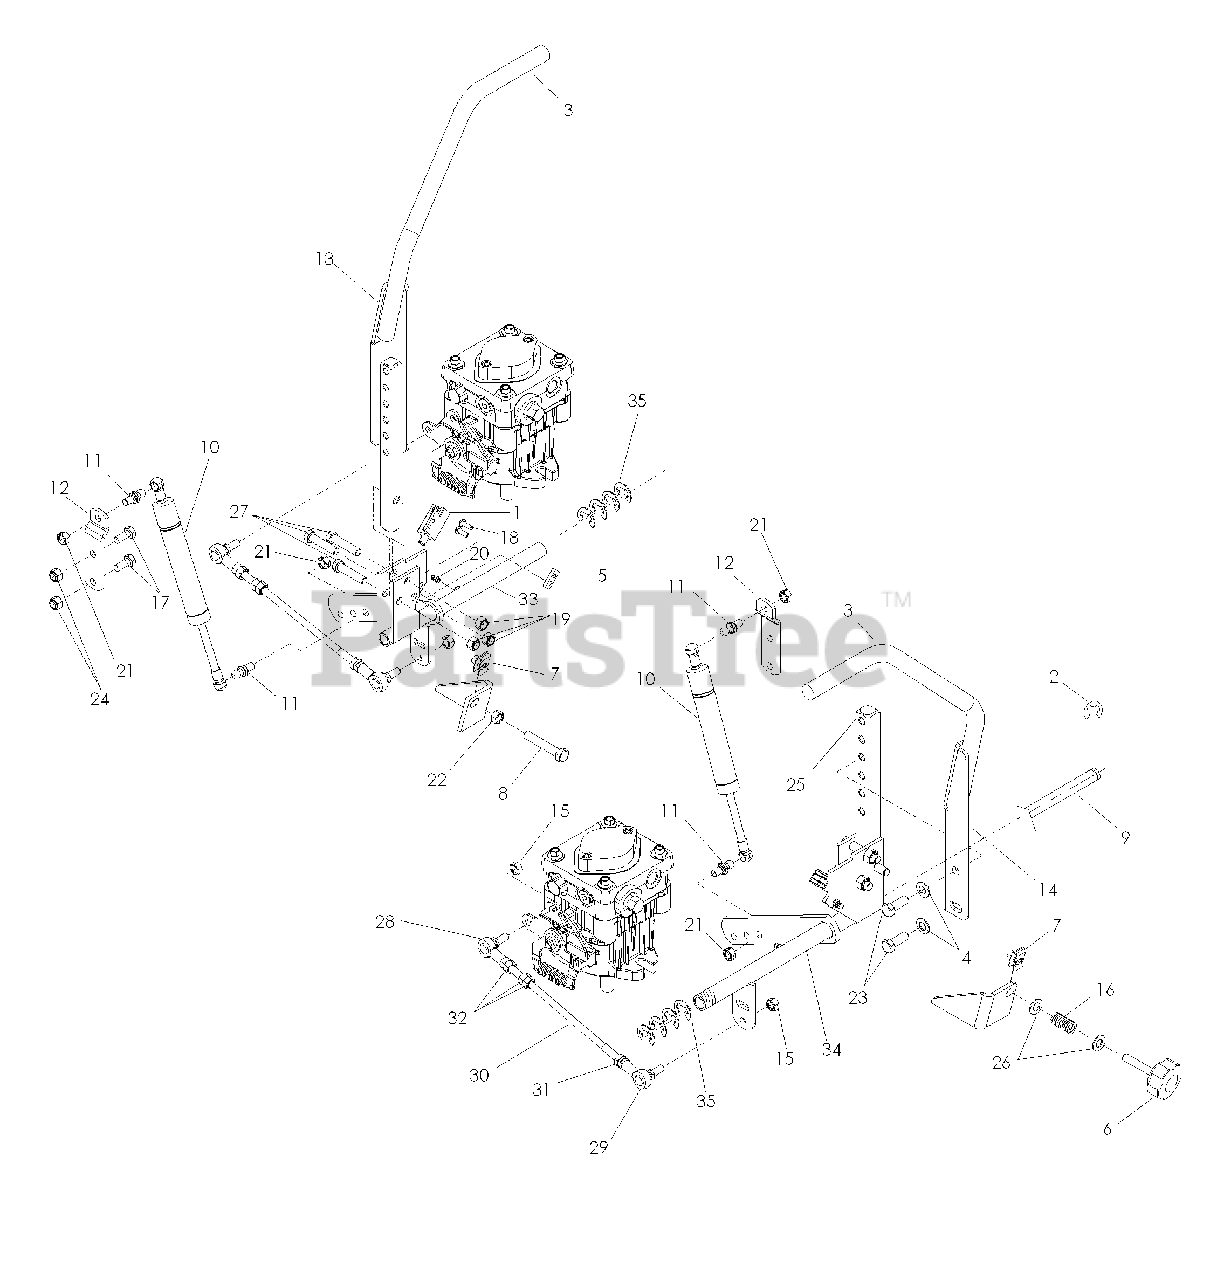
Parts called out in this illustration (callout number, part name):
1	SWITCH, INTERLOCK
2	E-RING, 1/2
3	CUSHION, DRIVE LEVER
4	WASHER, 3/8, SPRING, SPEC
5	TAPPED PLATE
6	ADJUSTMENT KNOB
7	NUT, 5/16-18, U-TYPE
8	HCS, 5/16-18 x 1 3/4, TPBLT
9	CONTROL SHAFT
12	DAMPENER ARM
13	DRIVE LEVER, RIGHT
14	DRIVE LEVER, LEFT
15	NUT, 5/16, NYLOC
16	COMPRESSION SPRING
17	HCS 5/16-18 x 3/4
18	SCREW, #10-24 x 5/8
19	NUT 3/8-16 HEX NYLOC
20	ZERK, STRAIGHT 1/4-28
21	NUT, 5/16-18, CENTERLOCK
22	NUT, 5/16 -18
23	HCS 3/8-16 x 1
24	NUT 5/16-18 HEX NYLOC
25	ARM CONTROL SHAFT
26	WASHER, 5/16
27	HCS, 3/8 -16 x 1 3/4
28	ROD END, SPHERICAL, RT
29	ROD END, SPHERICAL, LT
31	NUT, 5/16, JAM, LH
33	CONTROL ARM ASSEM, RT
34	CONTROL ARM ASSEM, LT
35	E-RING, 5/8
